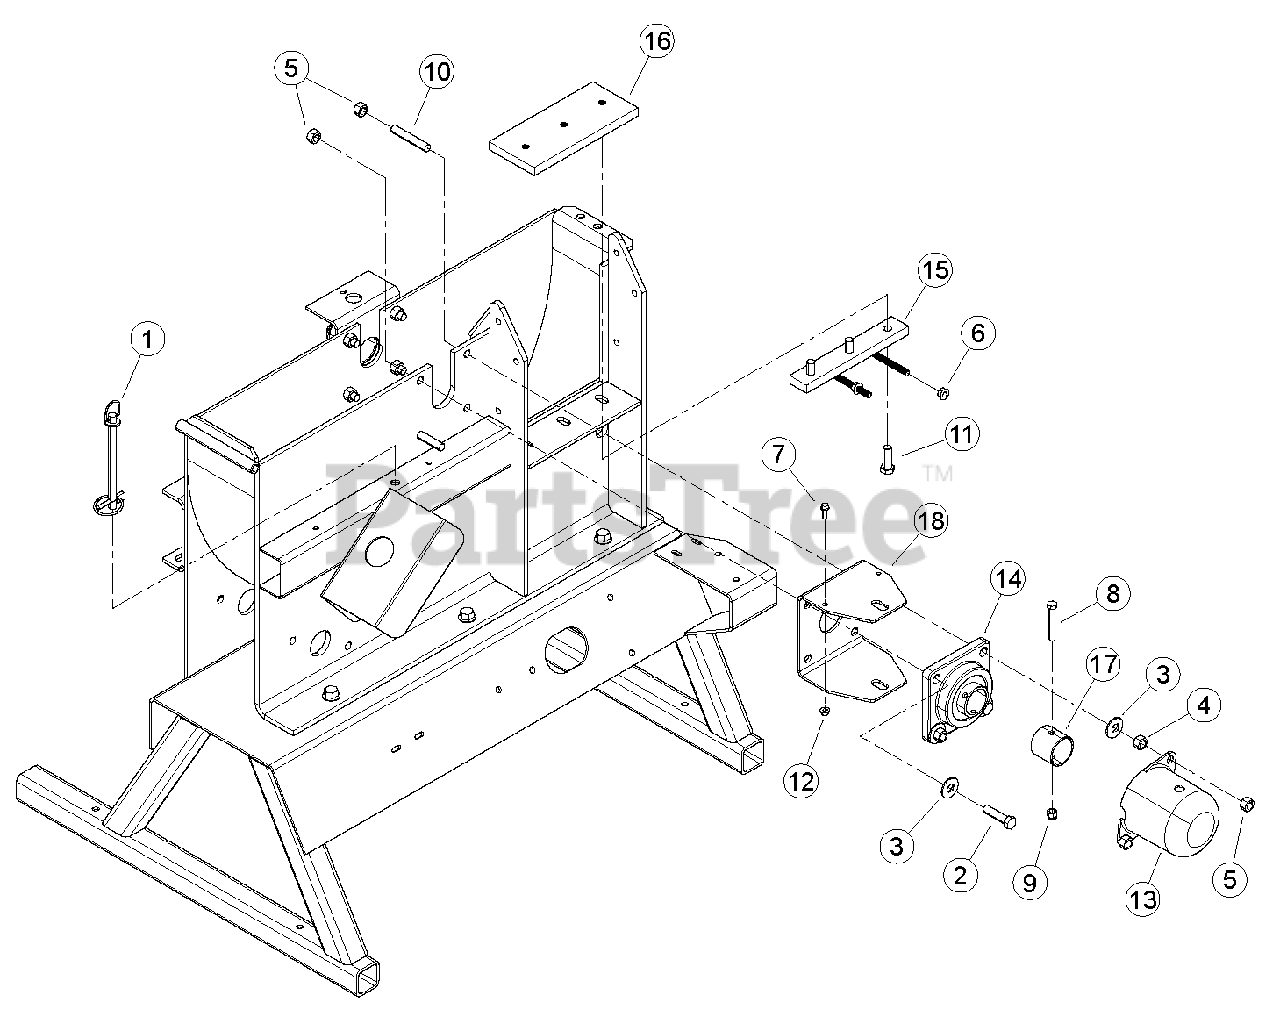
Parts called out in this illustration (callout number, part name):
1	PIN, HITCH 1/2 X 6-1/2 W LYNCH
2	BOLT, 1/2-13 X 2 GR5 HEX CAPSCREW
3	WASHER, 1/2 FLAT
4	NUT, 1/2-13 HEX
5	NUT, 1/2-13 GR5 CENTERLOCK GRB
6	NUT, 3/8-16 SERRATED FLANGE
7	BOLT, 1/4-20 X 3/4 HWH GR5 CZP
8	BOLT 3/8 X 2-1/2 GR5 HHCS ZP
9	NUT, 3/8-16 NE NYLOCK
10	STUD, 1/2"-13 X 3"LG B7 ZP
11	BOLT, 1/2 X 1-1/2 GR8 NC ZP HEX HD
12	NUT, 1/4-20 NYLOCK FLANGE
13	CAP, LARGE SHAFT
14	BEARING, 1-3/4 4 BOLT FLANGE
15	WELDMENT, BLOCK ADJUSTOR
16	PLATE, CHIPPER BOTTOM
17	COLLAR, CHIPPER LOCK
18	BRACKET, ROTOR LOCK
